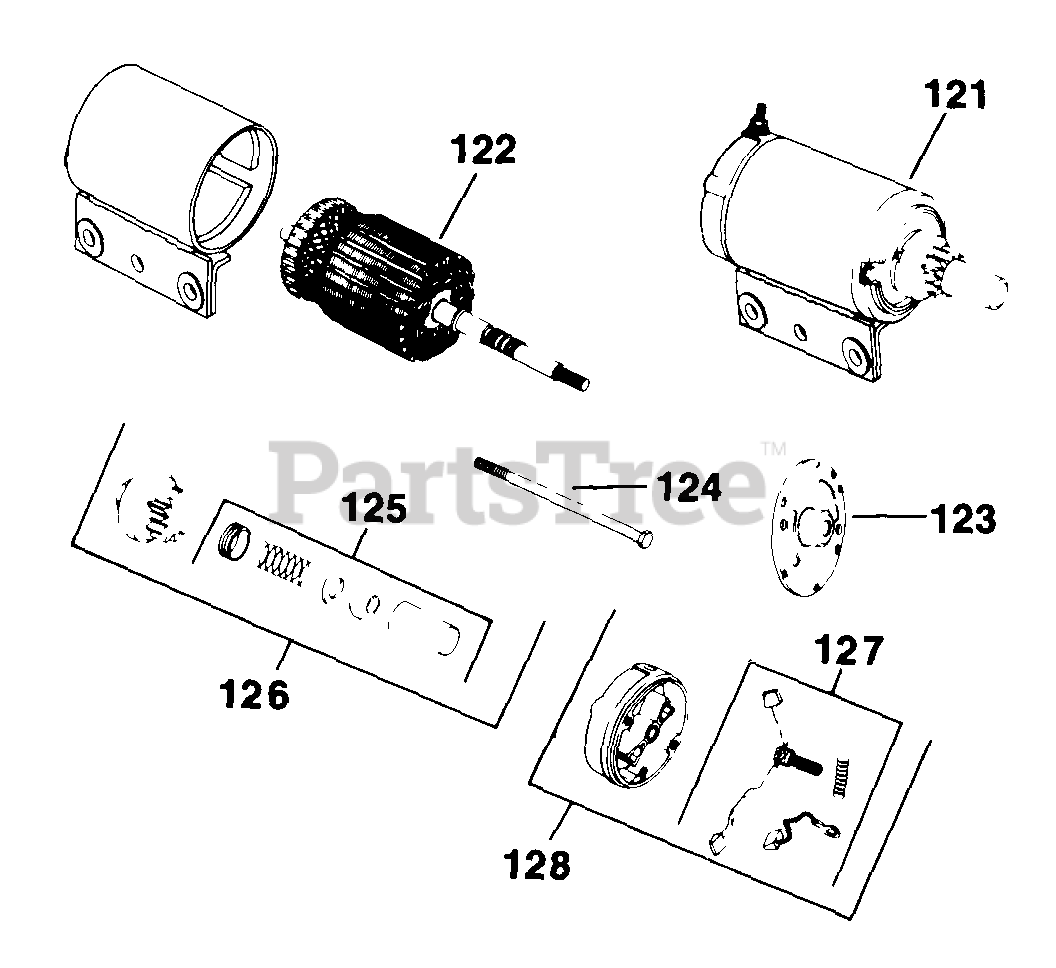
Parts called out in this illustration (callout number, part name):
121	STARTER - USE 45 098 09
122	ARMATURE - DISCONTINUED
123	CAP - USE 45 081 05
127	KIT - USE 52 755 15
128	CAP - DISCONTINUED
